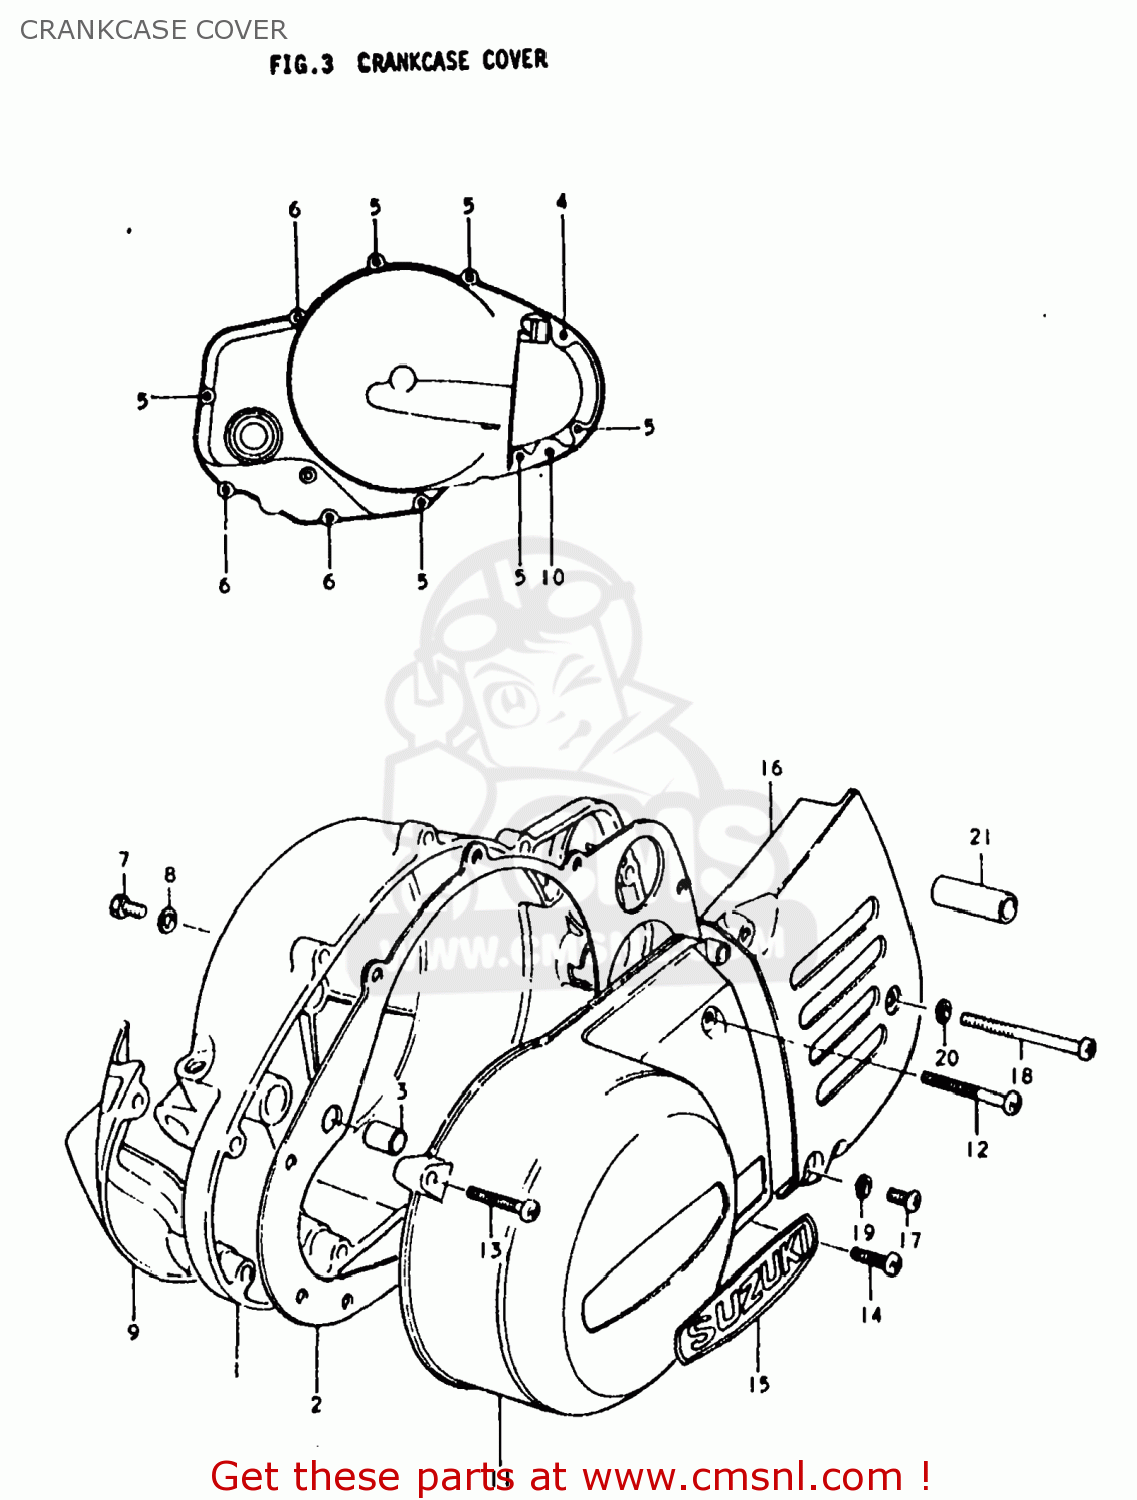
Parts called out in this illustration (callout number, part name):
1	COVER,CLUTCH
2	GASKET,CLUTCH COVER (MCA)
3	PIN
4	SCREW
5	SCREW
6	SCREW
7	SCREW(6X10)
8	GASKET(6.2X11X1) (NAS)
9	COVER,CLUTCH RELEASE A
10	SCREW
11	COVER,MAGNETO
12	SCREW (6X35)
13	SCREW
14	SCREW
15	EMBLEM,MAGNETO COVER
16	COVER,SPROCKET
17	SCREW
18	SCREW 6X60
19	LOCK WASHER
20	LOCK WASHER
21	CUSHION
